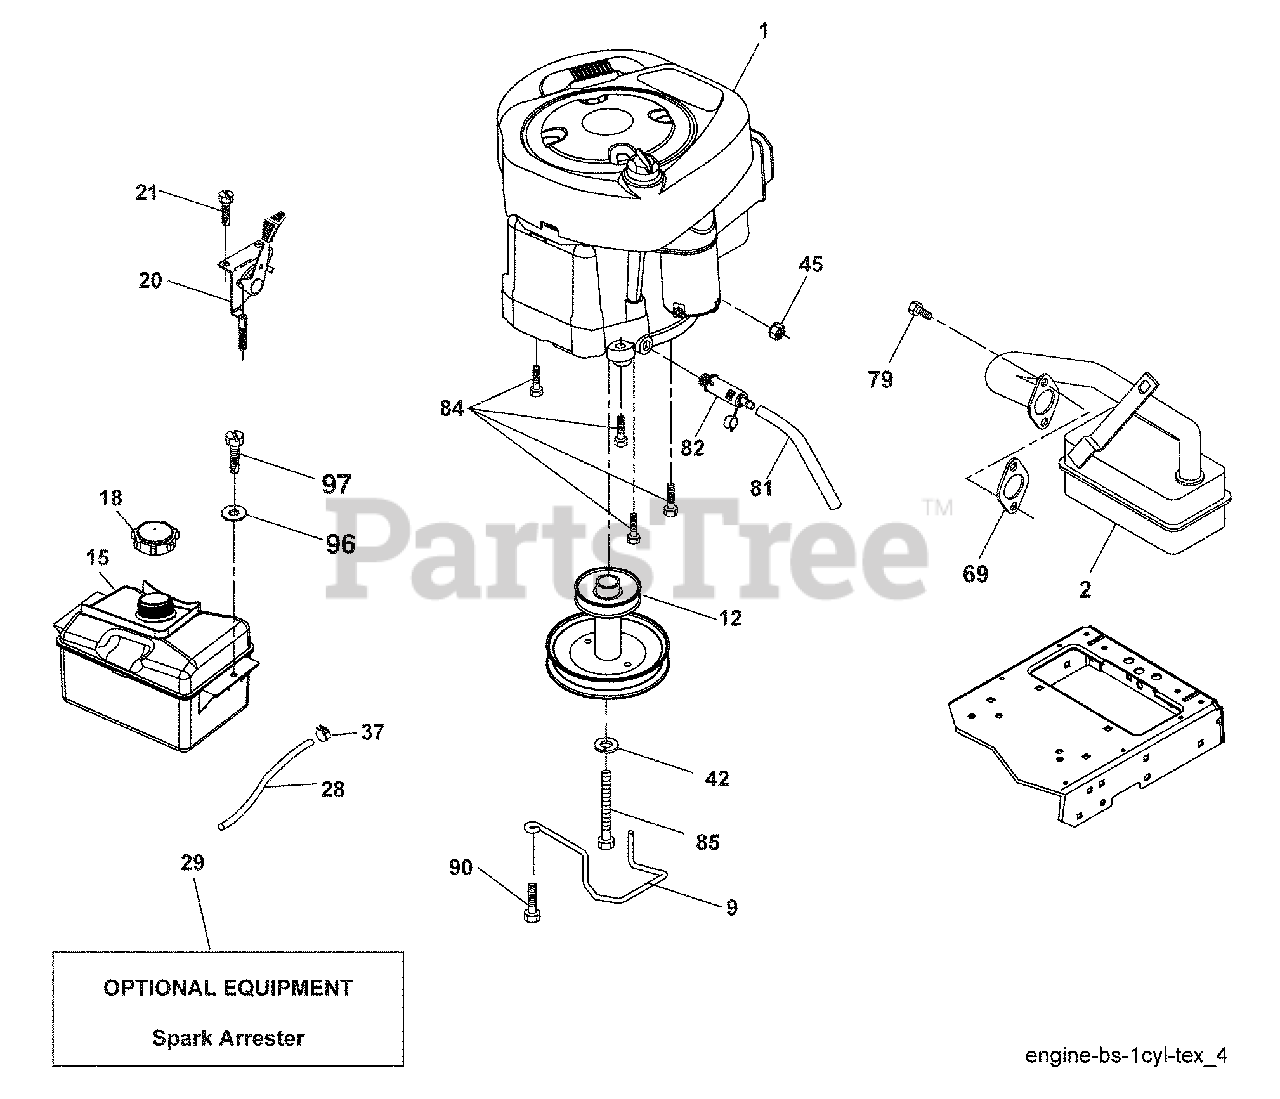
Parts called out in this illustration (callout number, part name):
9	Keeper Belt Engine
12	Pulley Engine
15	Tank Fuel 1.5
18	Cap Asm
20	Control Throttle
21	Screw 10 x 3/4 Single Lead-Hex
28	Fuel Line
29	Spark Arrester Kit
37	Clamp Hose
42	Washer Lock 7/16
45	Nut Keps Hex 1/4-20 unc
69	Gasket
79	Screw Socket 5/16-18 x .75
81	Tube Drain Oil Easy
82	Plug Drain Oil
84	Screw 3/8-16 x 1-1/4
85	Bolt Hex 7/16-20 x 4 x GR5-1.5
90	Screw 3/8-16 x 1
96	Washer 9/32 x 7/8 x 16 Ga.
97	Screw 1/4-20 x 3/4
